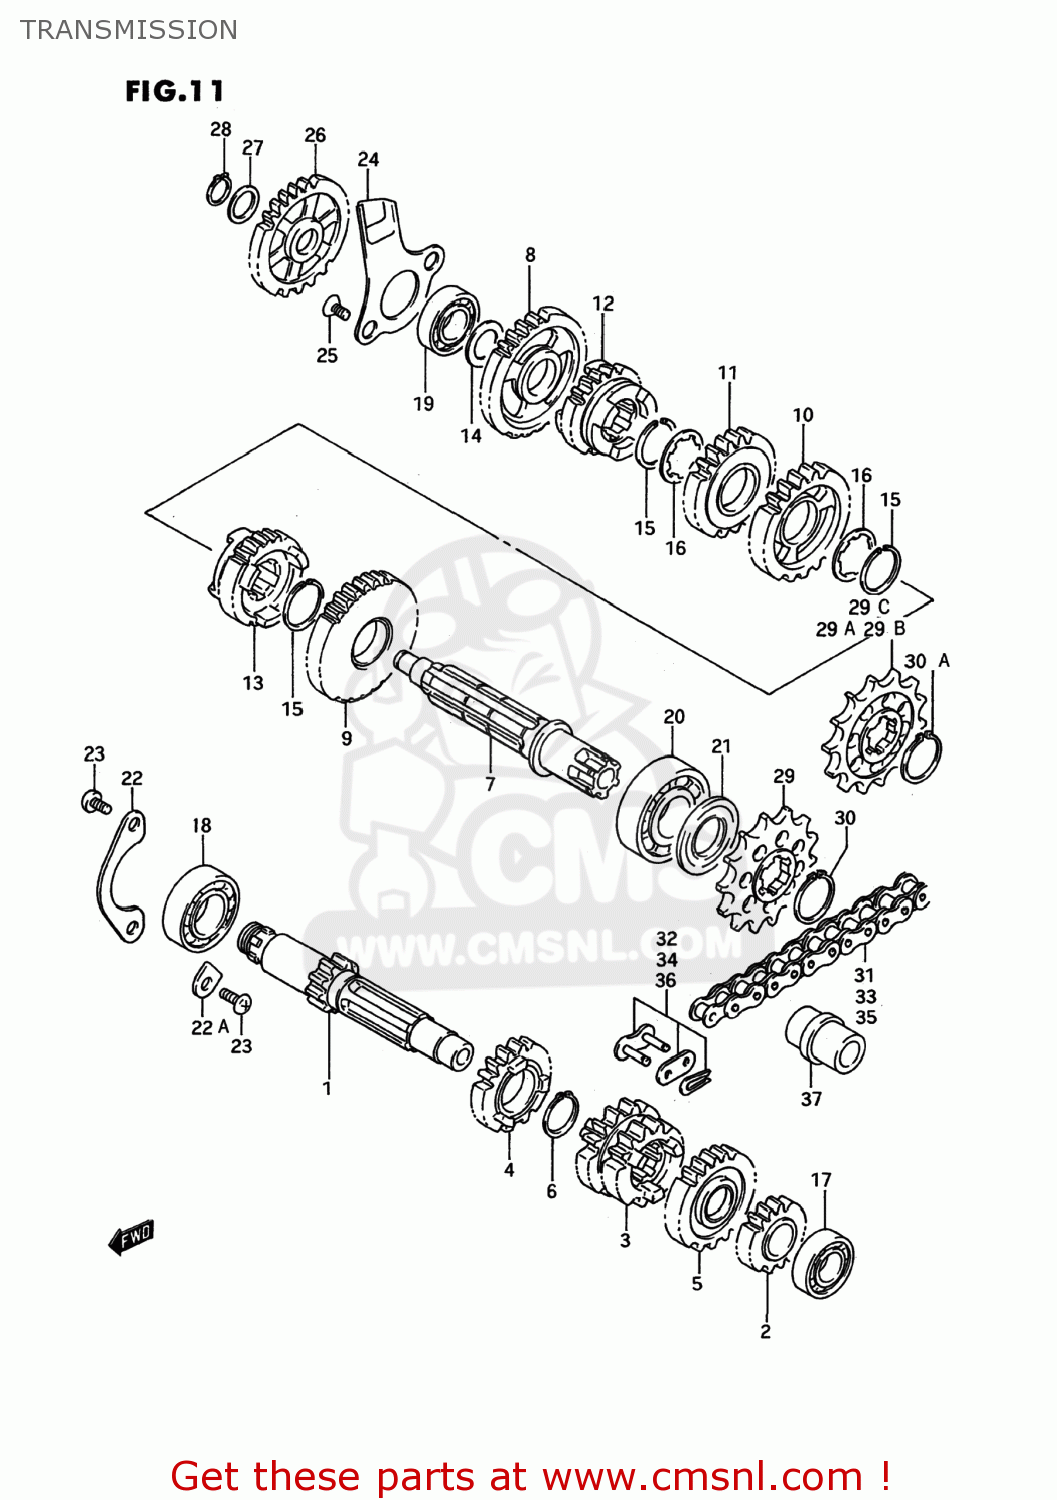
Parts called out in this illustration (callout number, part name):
1	SHAFT,COUNTER
2	GEAR,2ND DRIVE (NT:15)
3	GEAR,THIRD/FOURTH DRIVE
4	GEAR,FIFTH DRIVE
5	GEAR,6TH DRIVE
6	CIRCLIP
7	SHAFT,DRIVE
8	GEAR,FIRST DRIVEN
9	GEAR,SECOND DRIVEN
10	GEAR,THIRD DRIVEN
11	GEAR,FOURTH DRIVEN
12	GEAR,FIFTH DRIVEN
13	GEAR,SIXTH DRIVE (NT:23)
14	WASHER,THRUST
15	CIRCLIP
16	WASHER,LOCK
17	BEARING
18	BEARING(20X42X12)
19	BEARING
20	BEARING(20X47X14)
21	OIL SEAL (20X35X5)
22	RETAINER,CNTR SHAFT BEARING
22A	RETAINER
23	SCREW
24	RETAINER,DRIVESHAFT
25	SCREW
26	GEAR,KICK STARTER IDLE
27	SHIM
28	CIRCLIP,12 MM
29	SPROCKET,ENGINE
29A	SPROCKET,ENGINE
29B	SPROCKET,ENGINE(NT:14)
29C	SPROCKET,ENGINE(NT:13)
30	CIRCLIP
30A	CIRCLIP
31	CHAIN ASSEMBLY,DRIVE
32	JOINT (RK)
33	CHAIN ASSEMBLY,DRIVE
34	JOINT,CHAIN
35	CHAIN,DRIVE(428G2X118L)
36	JOINT SET,CHAIN
37	CUSHION
